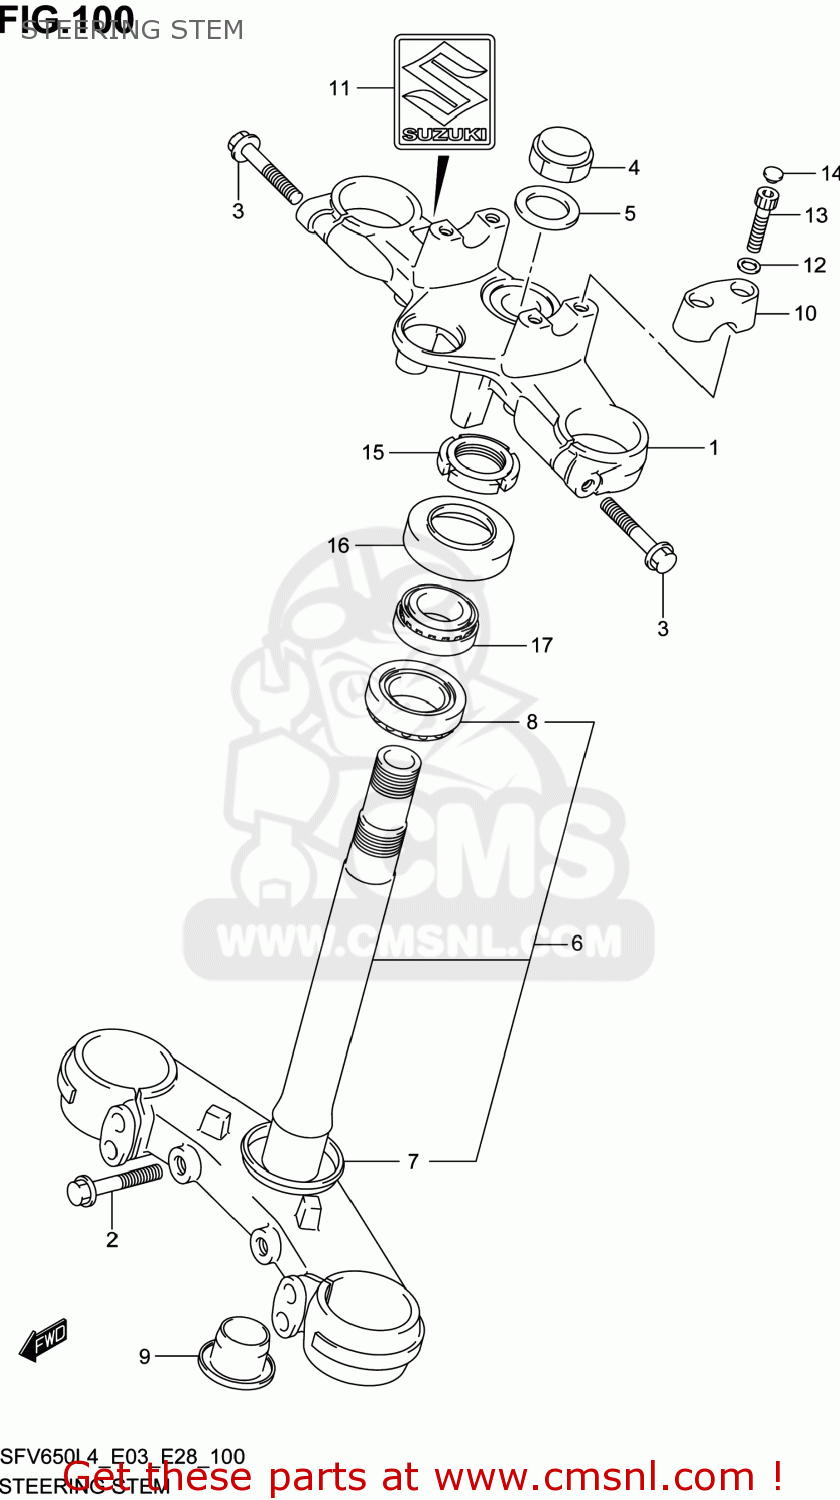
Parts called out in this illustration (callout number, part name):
1	HEAD,STEERING STEM
2	BOLT
3	BOLT
4	NUT,CAP
5	WASHER
6	STEM,STEERING
7	SEAL,STEERING LWR
8	BEARING(30X55X17)
9	CAP
10	HOLDER,HANDLE
11	EMBLEM,"S"
12	WASHER
13	BOLT
14	CAP(OD:11)
15	NUT,STEERING STEM
16	DUST SEAL,STEERING UPR
17	BEARING(25X47X15)
